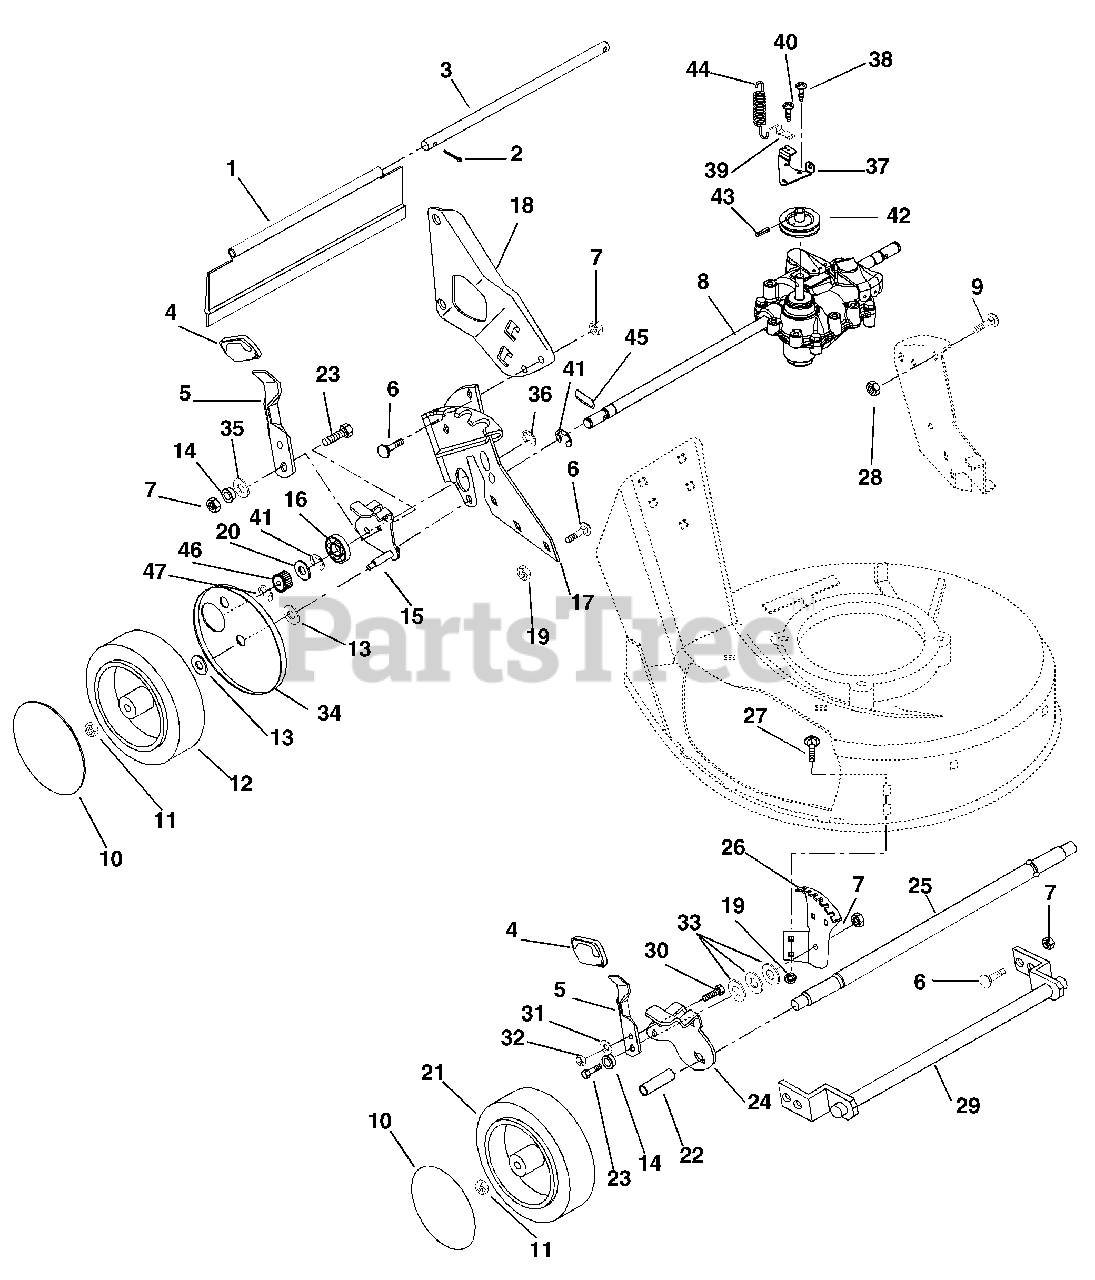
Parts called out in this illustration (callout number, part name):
1	Rear Protective Guard, Self Propelled
2	Pin-Cotter .06 x .50
5	Height Adjustment Lever
6	Bolt-Round Head Square Neck .31-18 x .62
7	Nut-Locking-Center .31-18
8	Transmission-Tuff Torque
9	Bolt-Round Head Square Neck .31-18 x 1.00
10	Cover-Wheel
11	Nut-Jam-Locking-Nylon .438-14
12	Wheel-Rear with Gear Teeth
13	Washer-Flat-Steel .50 x 1.25 x .083
14	Bushing-Flange .312 x .500 x .344 x .880
15	Adjuster-Height Weldment Assembly Right Hand
15	Adjuster-Height Weldment Assembly Left Hand
16	Bearing-Ball .500 x 1.38 x .437
17	Rear Quadrant-Left Hand
17	Rear Quadrant-Right Hand
18	Bracket-Handlebar Mounting-Right Hand
18	Bracket-Handlebar Mounting-Left Hand
19	Nut-Locking-Flanged .31-18
20	Washer-Flat-Steel .505 x .880 x .079
21	Wheel-Front
22	Spacer .52 x .75 x .50
23	Bolt-Hex .31-18 x 1.00 Grade 5
24	Left Hand Adjuster Bracket
24	Right Hand Adjuster Bracket
25	Axle-Front
26	Front Quadrant, Left Hand
26	Front Quadrant, Right Hand
27	Bolt-Round Head Square Neck .31-18 x .50
28	Nut-Locking-Nylon .31-18
29	De-Thatcher Retainer Weldment
30	Bolt-Hex .25-20 x .50 Grade 5
31	Washer-Flat-Steel .281 x .62 x .065
32	Nut-Locking-Center .25-20
33	Washer-Flat-Steel .344 x 1.375 x .075
34	Cover-Wheel Inner-Left Hand
34	Cover-Wheel Inner-Right Hand
35	Washer-Flat-Steel .531 x 1.06 x .095
36	Ring-Retaining-External 1.625 x .062
37	Bracket-Transmission Mount
38	Screw-Tapping .25-20 x .50
39	Clip
40	Screw-Tapping 8-32 x .50
41	Ring-Retaining-External .500 x .035
42	Sheave 3.75 x .395 with Hub
43	Pin-Roll .188 X .88
44	Spring-Tension .051 x .50 x 5.30 x Weldment 12
45	Key Ratchet
46	Pinion/Ratchet-Left Hand 15
46	Pinion/Ratchet-Right Hand 15
47	Ring-Retaining-External .438 x .025
